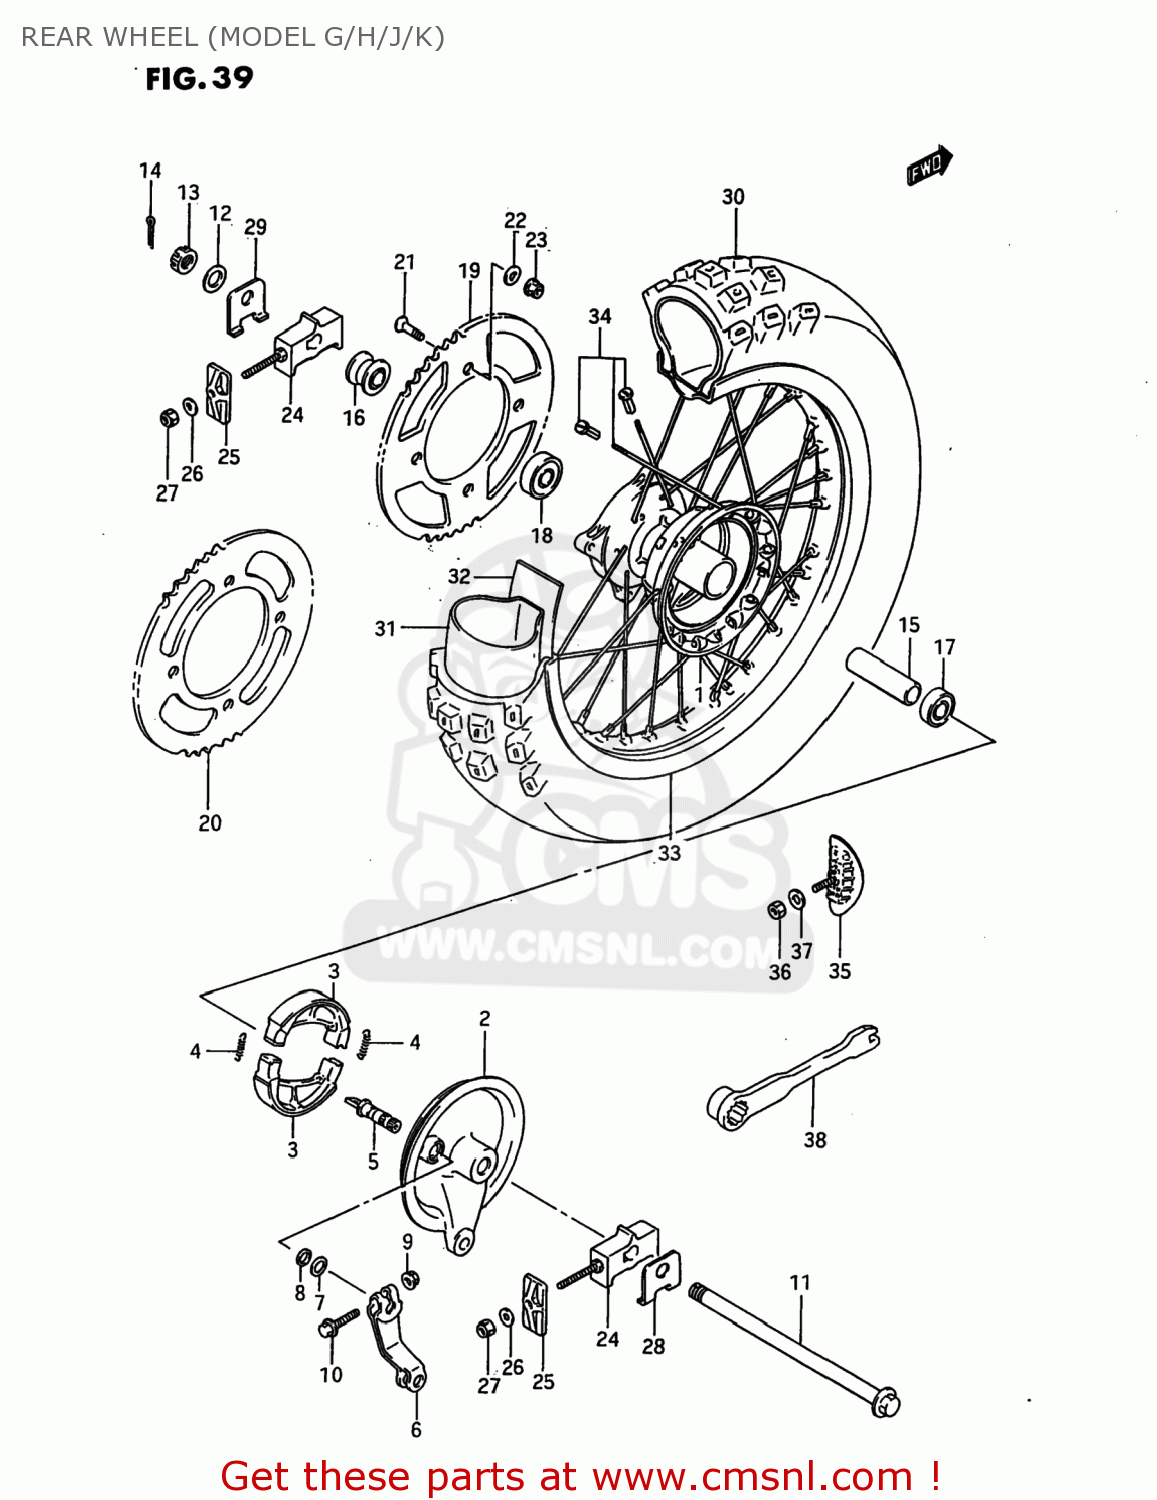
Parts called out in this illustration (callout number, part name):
1	HUB,REAR
2	PANEL,REAR HUB
3	SHOE,BRAKE
4	SPRING(L:34)
5	CAM,BRAKE
6	LEVER,RR BRAKE CAM
7	WASHER(12.5X20X1)
8	O RING(D:2.5,ID:11.4)
9	NUT
10	BOLT
11	AXLE,REAR
12	WASHER
13	NUT
14	COTTER PIN
15	SPACER(15.3X21.7X77)
16	SPACER,L
17	BEARING
18	BEARING
19	SPROCKET,RR(NT:50)
20	SPROCKET,RR(49T)
21	BOLT(8X30.5)
22	WASHER
23	NUT
24	ADJUSTER,CHAIN
25	PLATE,CHAIN ADJUSTER
26	WASHER
27	NUT 6MM
28	WASHER,CHAIN ADJUSTER RH
29	WASHER,CHAIN ADJUSTER,L
30	TIRE
31	TUBE ASSEMBLY,WHEEL,INNER
32	PROTECTOR,INNER TUBE
33	RIM,REAR WHEEL (1.60X14)
34	SPOKE SET
35	STOPPER,BEAD
36	NUT
37	WASHER
38	SPARK PLUG WRENCH 21 & SPANNER 5.1
